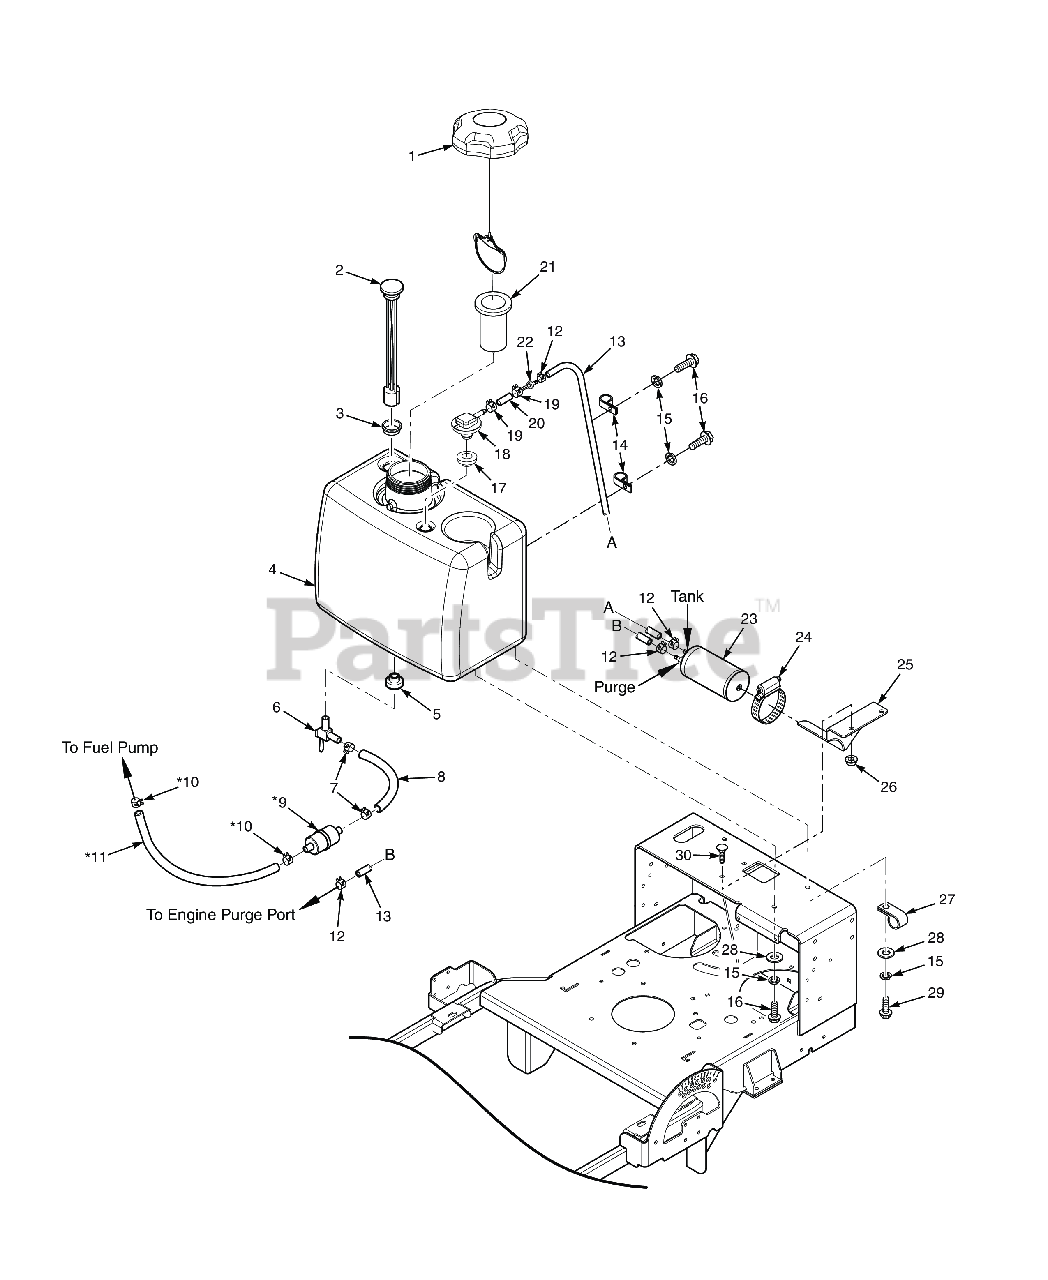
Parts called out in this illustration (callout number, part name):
1	Fuel Cap w/ Tether (E.P.A.)
2	Fuel Gauge Assembly
3	Grommet, Fuel Gauge
4	Fuel Tank Assembly (incl. #2, 3, 5, 6, 17, 18)
5	Bushing, 0.56" Dia. Viton
6	Valve, Fuel Shut Off w/Screen
7	Clamp, Fuel Hose 1/4" Hose I.D.
8	Fuel Hose, 1/4" I.D. Non-Perm (791DFI Fuel Return) - Order by Inch
9	Fuel Filter
10	Clamp, Fuel Hose
11	Fuel Hose
12	Clamp, Vapor Recovery Hose 3/16"
13	Hose, Vapor Recovery 3/16" (order by inch)
14	Clamp, Cable - .375 Dia.
15	Lockwasher, 5/16 (.317 x .586 x .078) Helical Spring
16	BOLT, SERRATED FLANGE HEX HEAD 5/16-18 X 3/4"
17	Grommet, Viton,
18	Remote Vent, No Valve
19	CLAMP, FUEL HOSE(KAWASAKI ONLY)
20	Hose, 1/4" Vapor Recovery (order by inch)
21	Tube, Fuel Tank Insert - 4"
22	Mender, 1/4 x 3/16 w/0.02 Hole
23	Carbon Canister - SVR-36A / SVR-48V
24	Clamp, 3-1/2" Max. Dia.
25	Bracket, Canister Mounting
26	Nut, Serrated Flange 5/16-18 (Right Front Engine Mounting, Briggs and Kohler Only)
27	Clamp, Cable 1/2" I.D.
28	Flatwasher, 5/16-.375 x .875 x .083 (35BV & 37BV-EFI)
29	Bolt, Heax Head 5/16-18 x 1" (48V / 52V)
30	Bolt, 5/16-18 x .75 RHSN Carriage
